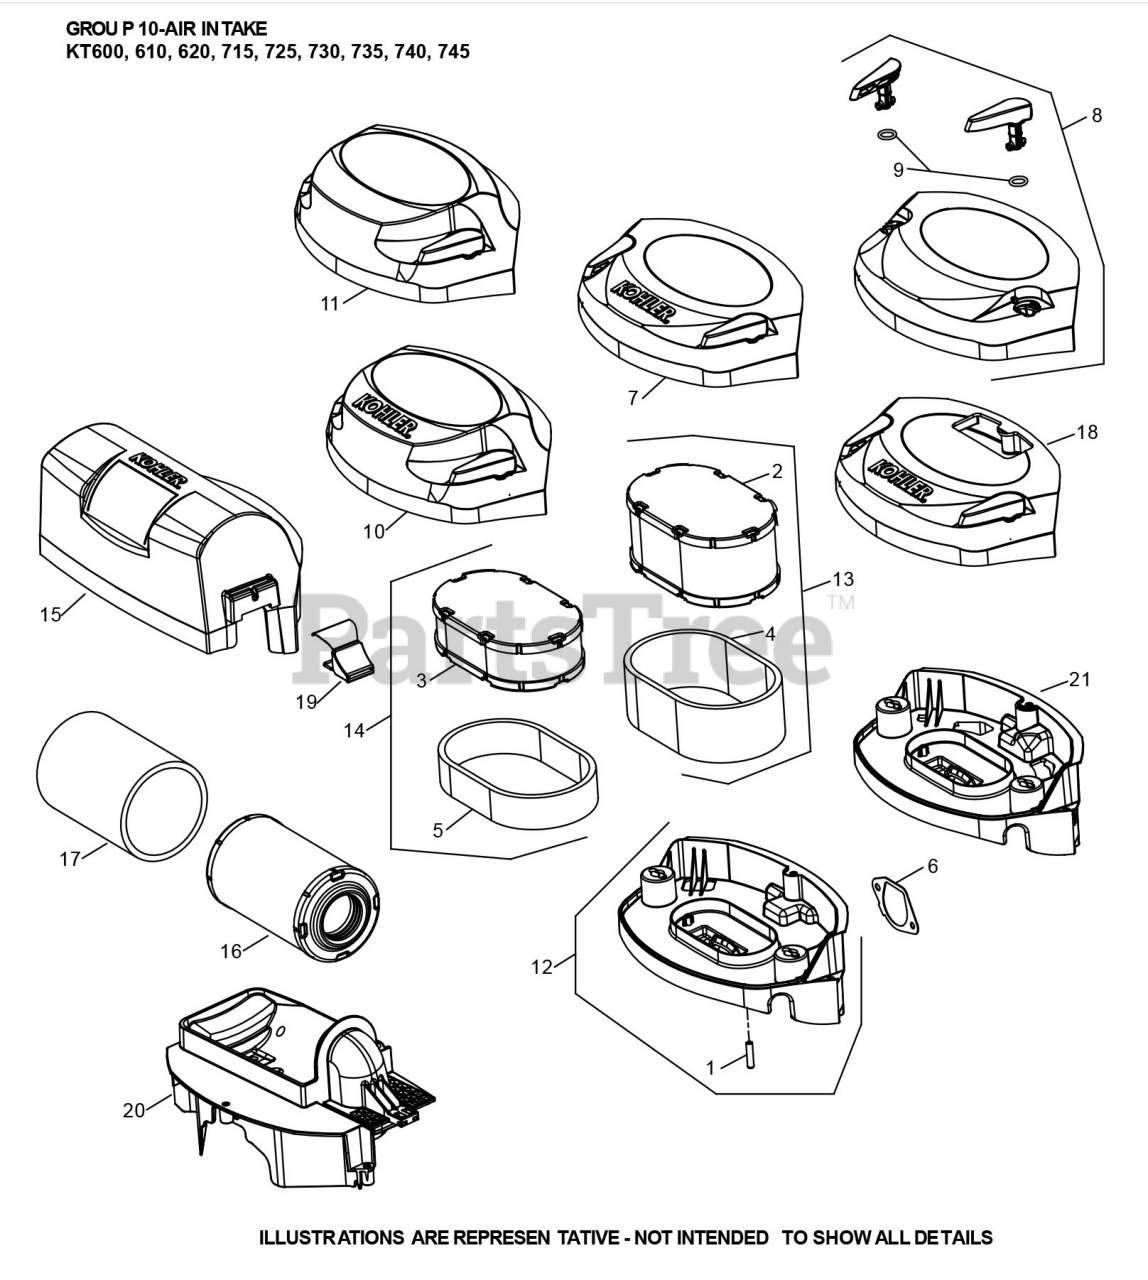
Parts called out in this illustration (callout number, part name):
3	FLTR KIT-AIR/PRECL
5	PRECLNR-FOAM (LPAC
6	GASKET-AIR CLNR BA
7	AIR CLEANER COVER ASSEMBLY
21	AIR CLEANER BASE ASSEMBLY
